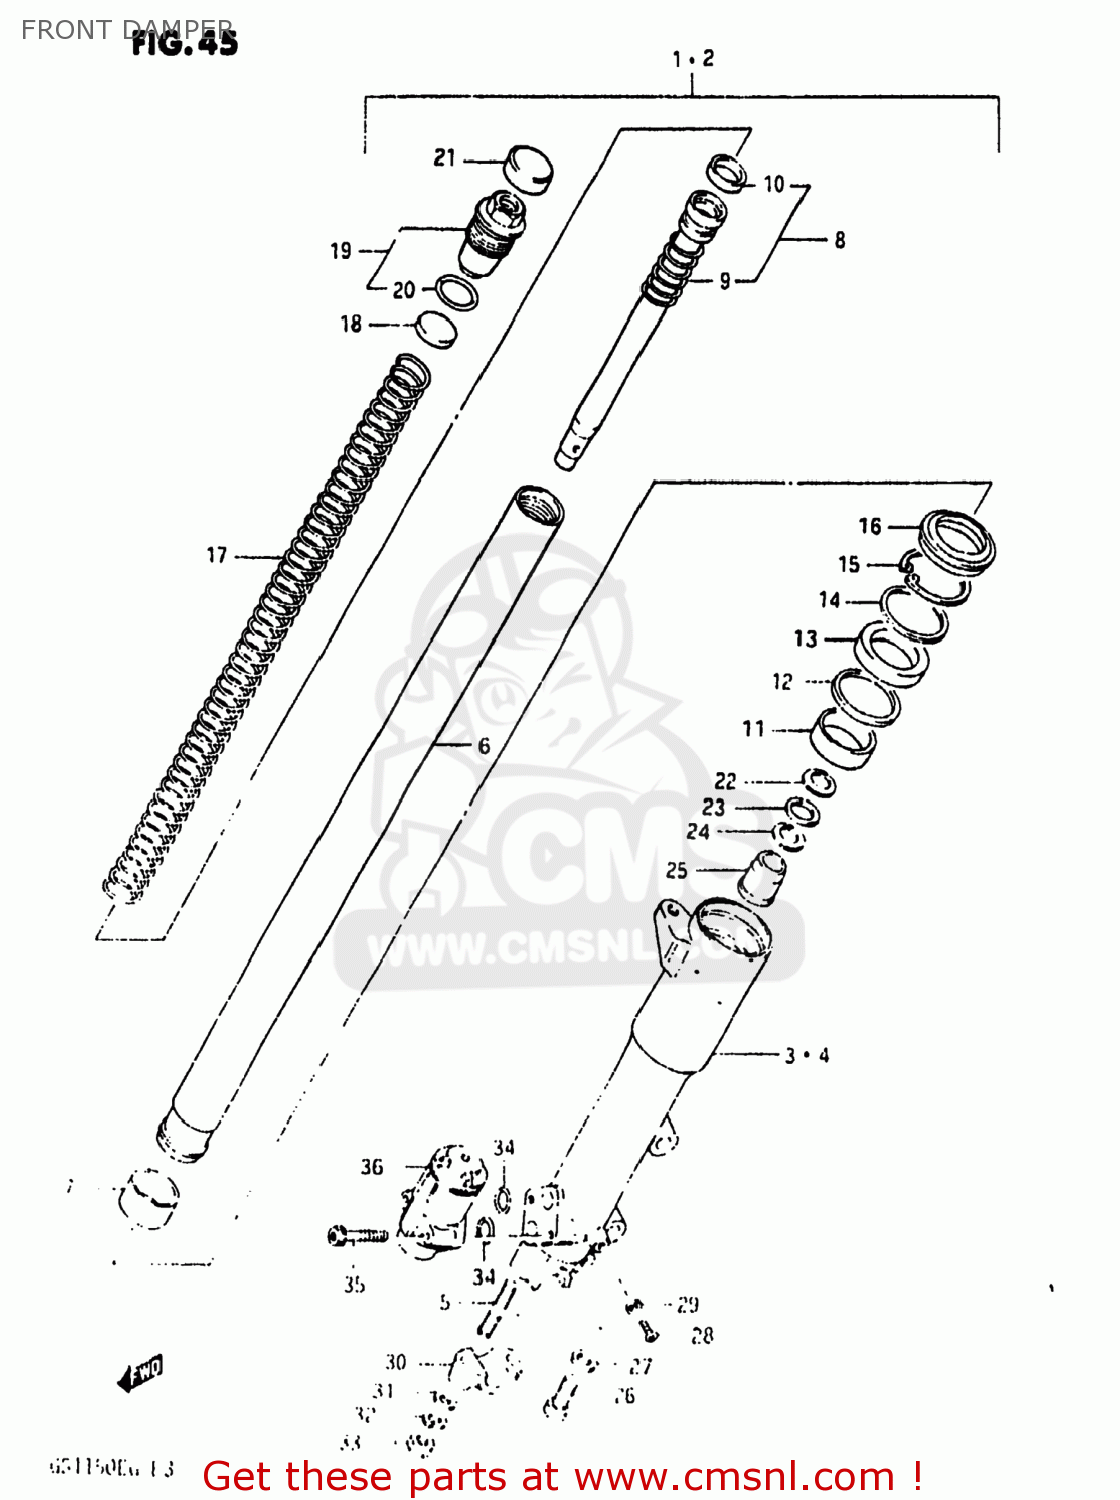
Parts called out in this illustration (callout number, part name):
1	DAMPER ASSEMBLY
2	DAMPER ASSEMBLY,LEFT
3	TUBE,FORK,OUTER,RIGHT
4	TUBE,FORK,LEFT,OUTER
5	STUD 8X30
6	TUBE,FORK,INNER
7	METAL,FR FORK PISTON
8	CYLINDER,FRONT FORK
9	SPRING,FORK REBOUND
10	RING,FR FORK PISTON
11	METAL,SLIDE
12	WASHER
13	SEAL,OIL
14	WASHER,FORK OIL SEAL
15	RING,STOPPER
16	SEAL,DUST
17	SPRING,FR FORK
18	WASHER
19	CAP
20	O RING
21	CAP,FORK INNER TUBE
22	SPRING,LEAF
23	WASHER
24	SPRING,LEAF
25	PIECE,OIL LOCK
26	BOLT,FORK CYLINDER(10X25)
27	GASKET (NAS)
28	SCREW
29	GASKET,DRAIN,PLUG (NAS)
30	HOLDER,AXLE
31	WASHER
32	WASHER,LOCK,8.
33	NUT
34	O RING
35	BOLT
36	PDF ASSEMBLY
